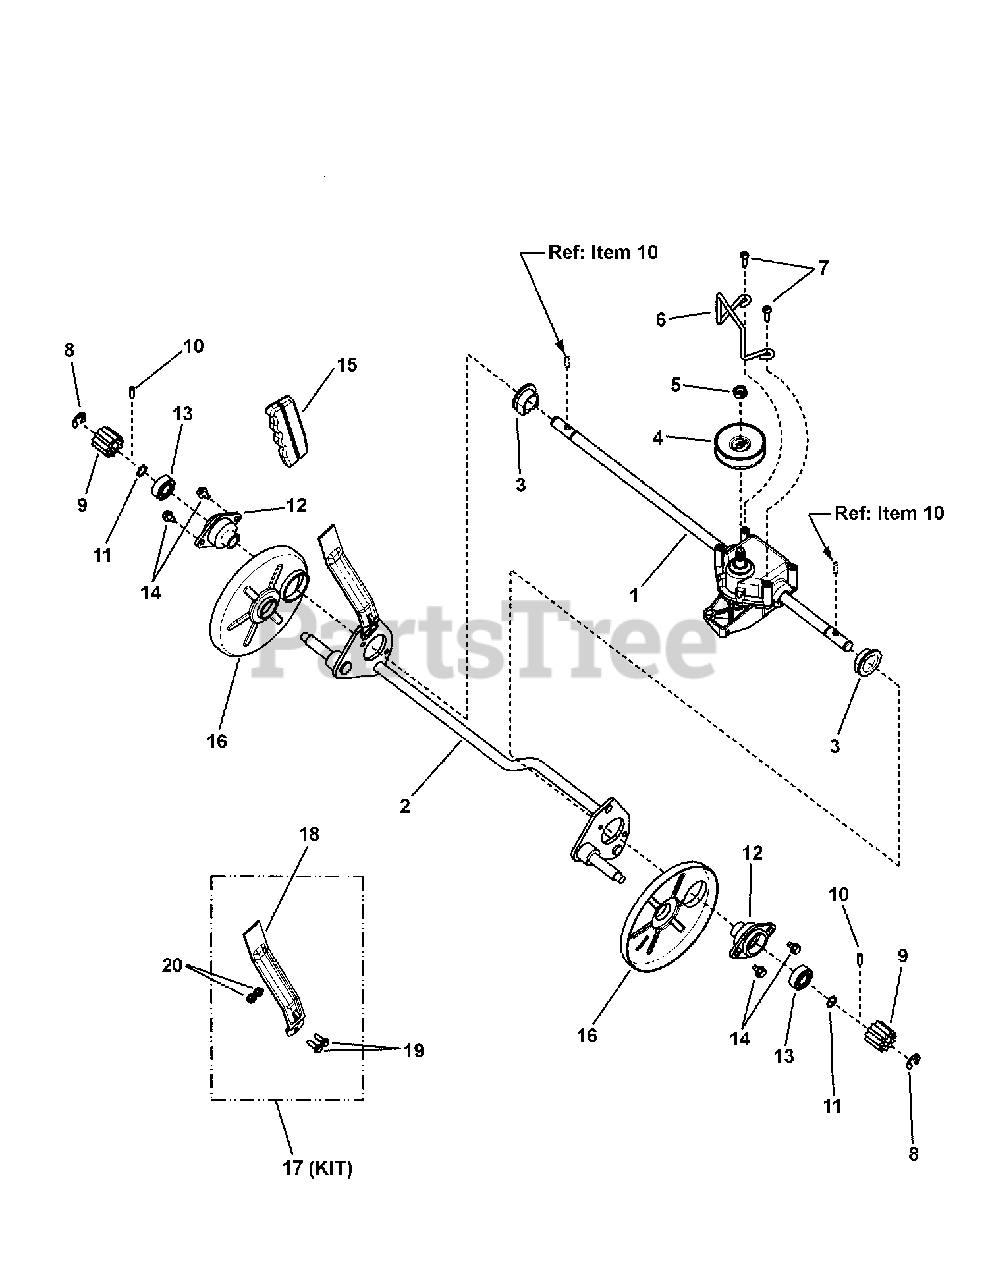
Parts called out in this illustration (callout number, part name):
1	TRANSMISSION, WBM, Cast Deck
2	WELDMENT, Rear Axle
3	BUSHING, Rear Axle (S/P)
4	PULLEY, Transmission
5	NUT, 3/8-16 Hex Center Lock (Jam)
6	BELT GUIDE, Transmission (Wireform)
7	SCREW, #10-16 x 3/4, Pan Head Self-Tap, Combo
8	RING, External Retaining
9	GEAR, Pinion
10	PIN, Axle
11	RETAINING RING
12	ASSY, Bearing Carrier
13	BALL BEARING, 1/2 ID x 1-1/8" OD
14	SCREW, 1/4-20 x 3/8" Hex Washer Head, Self-Tap
15	GRIP, Flat Bar (Black)
16	DUST SHIELD, Cast Deck
17	KIT, Height Adjusting Lever
18	LEVER, Height Adjusting (Black)
19	SCREW, #10-32 x 5/8" Hex Washer Self-Tap, GR5
20	NUT, #10-32 Hex Nyloc
